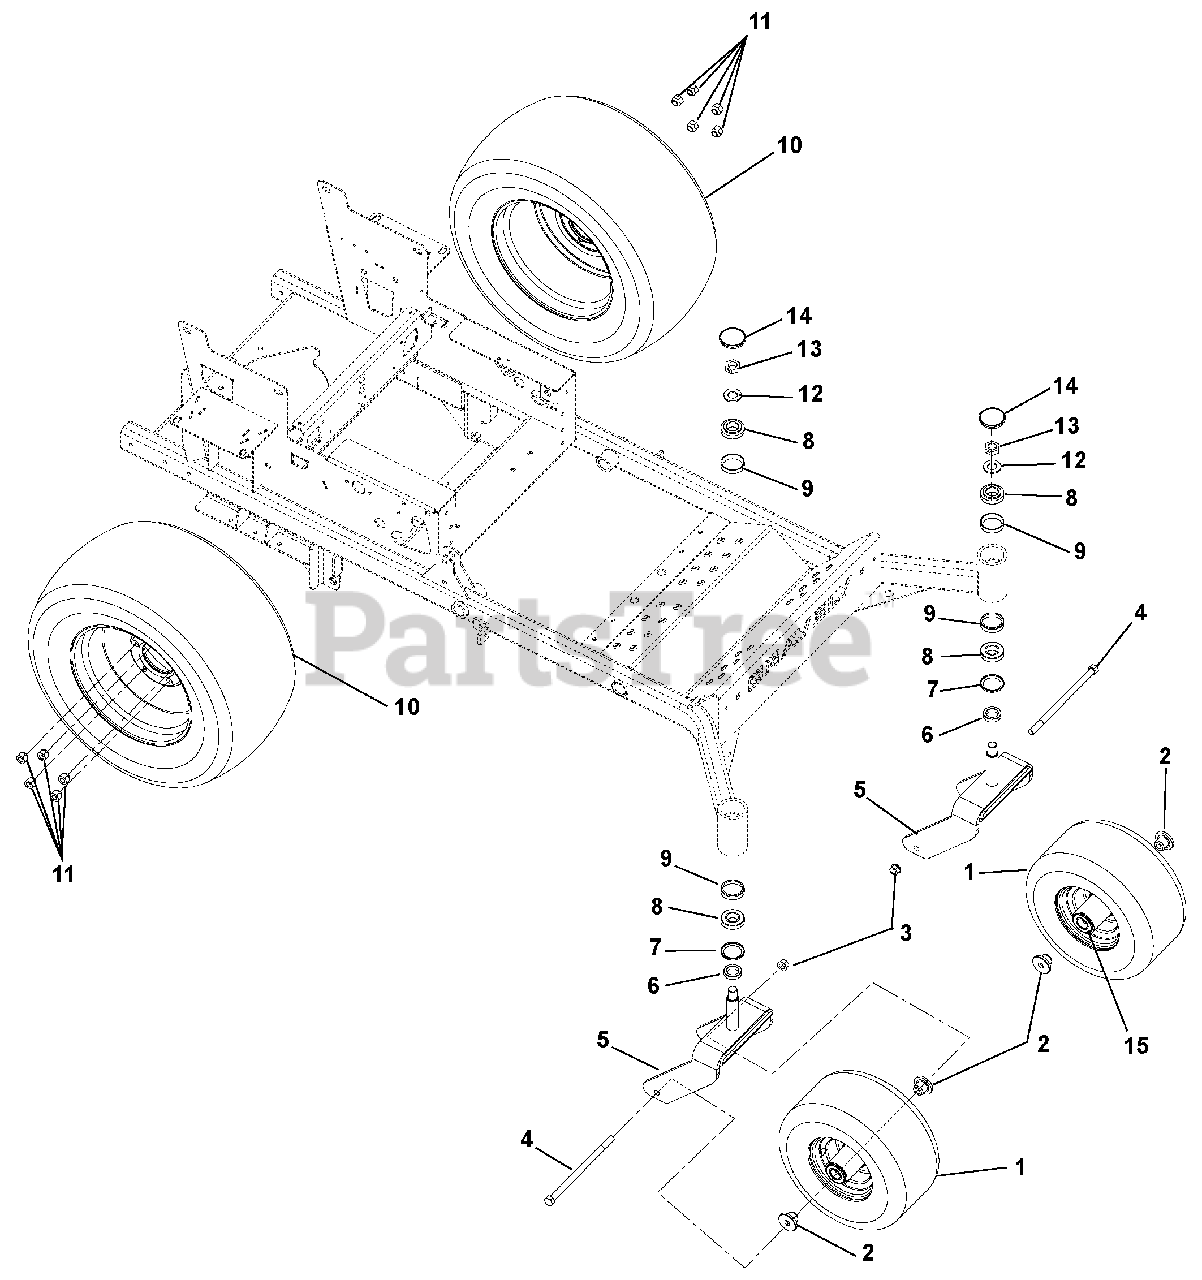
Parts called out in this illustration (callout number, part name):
1	Tire/Wheel Assembly, 13 x 6.50-6
2	Spacer, Front Wheel
3	Nut, .50-13 Nyloc Flange
4	Bolt, Hex .50-13 x 9.00
6	Spacer 1.258 x 1.75 x .550
7	Seal, Oil 1.75 x 2.332 x .312
8	Bearing, Cone 1.25 x .66
9	Bearing, Cup 2.328 x .465
10	Tire/Wheel Assembly, 23 x 10.50-12
11	Nut, Wheel .50-20 13/16 Across Flats, Automotive Type
12	Washer, Flat Steel .812 x 2.00 x .148
13	Nut, Jam Center-Lock .75-16
14	Cap, Dust
15	Bearing, 25 mm ID x 52 mm OD x 15 mm
